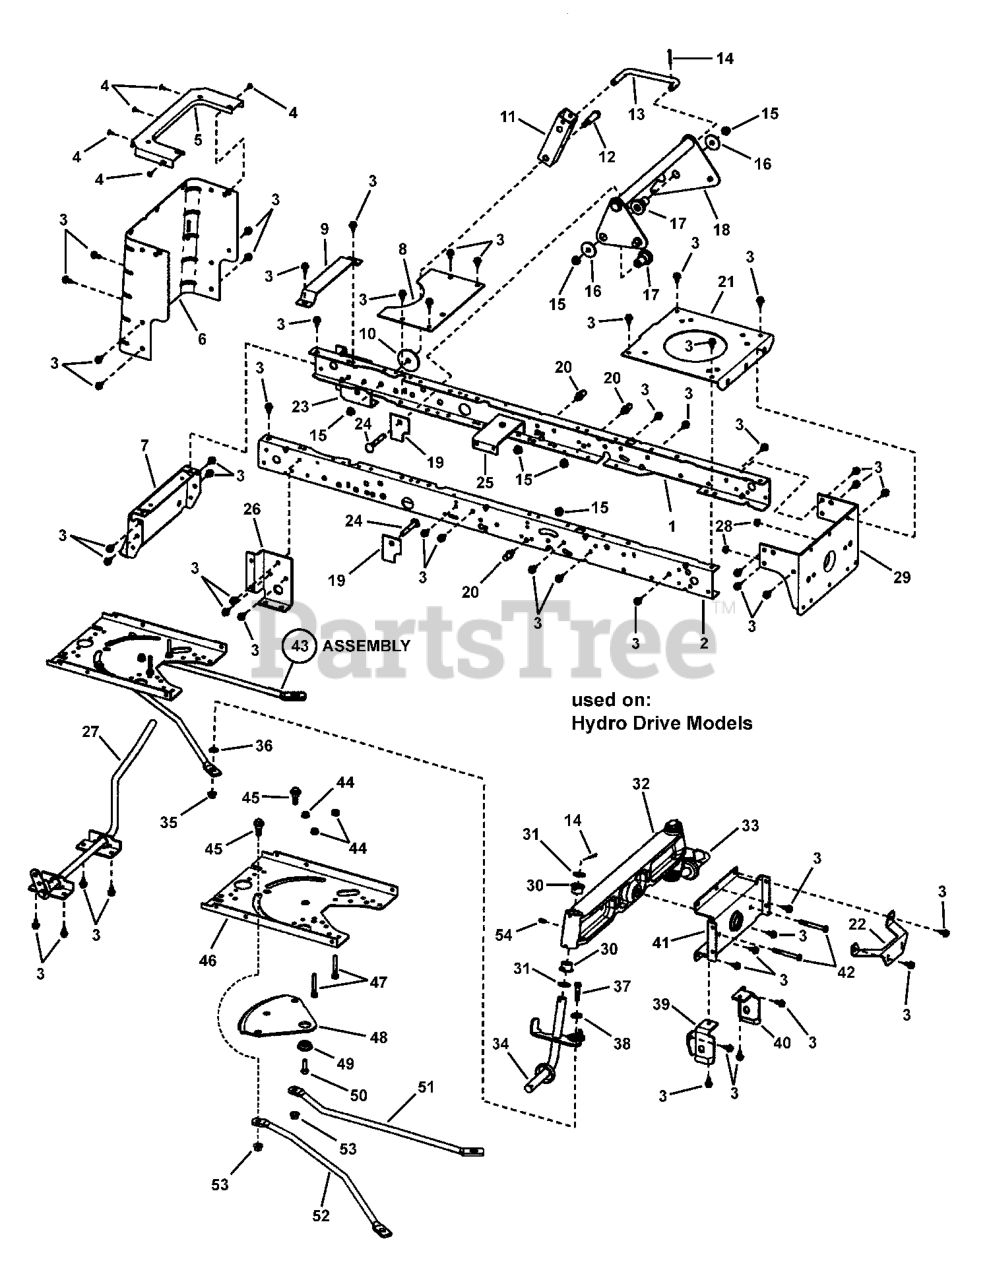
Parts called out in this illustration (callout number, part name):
1	RAIL, FRAME LH
2	RAIL, FRAME RH
3	SCREW, 5/16-18 x 3/4
4	SCREW, 10-24X.50 SELF-TAP SEMS
5	TOP - REAR PLATE
6	PLATE REAR
7	PLATE - HITCH
8	PLATE, IDLER PULLEY HYDRO GEAR
9	BRKT - BATTERY SUPPORT
10	WASHER PLAIN .406 X 2.25
11	BRACKET - PIVOT
12	SHOULDER BOLT, 1.563L X 0.75D X 9/16 X 3/8-16
13	LINK - LIFT HANDLE
14	PIN, COTTER 1/8 X 1.25 YZ
15	HFLN, 3/8-16 YZ
16	WASHER, 1-1/2 OD
17	SPACER - LIFTER PIVOT
18	LIFTER ASSY (WELDMENT)
19	PLATE STIFFENING
20	PIN - THREADED SHOULDER (3/8-16)
21	PLATE - ENGINE
22	BRACKET, MUFFLER MOUNTING
23	BRACKET - TRANSAXLE L.H.
24	RHSSNB, 3/8CX2-1/2
25	ASSY, IDLER BRKT (SECONDARY)
26	BRACKET - TRANSAXLE R.H.
27	ASSEMBLY - BRAKE LEVER (WELDMENT)
28	HFLN, 5/16-24 BZ
29	BRACKET - HANGER REAR
30	BEARING SPINDLE (3/4 I.D.)
31	WASHER, .77X1.13X.06
32	GT AXLE - CAST IRON
33	WELDMENT - SPINDLE LH
34	WELDMENT - SPINDLE RH
35	NUT, HEX FLANGE, 3/8-16 NC
36	FW, .41 X.82 X 16GA
37	BOLT, HEX, 3/8-16 UNC X 1.50 BRIGHT ZINC
38	WASHER, FLAT, 25/64" ID X 1" OD X 14 GA.
39	HANGER DECK RH
40	HANGER DECK LH
41	HANGER - AXLE
42	HHB, 5/16-24 X 2.75 BOLT
43	SECTOR GEAR ASSY (GEAR DRIVE - LT)
44	HFLN, 5/16-18 BZ
45	BOLT, SHOULDER 3/8-16
46	PLATE, STEERING MOUNT
47	SCREW - GUIDE (5/16-18 thread)
48	GEAR - SECTOR
49	BEARING - SECTOR GEAR
50	HHCS, 5/16-18 X 1 YZ
51	DRAG - LINK LH
52	DRAG - LINK RH
53	HFLN, 3/8-16 YZ
54	FITTING - LUBRICATION (1/4-20)
